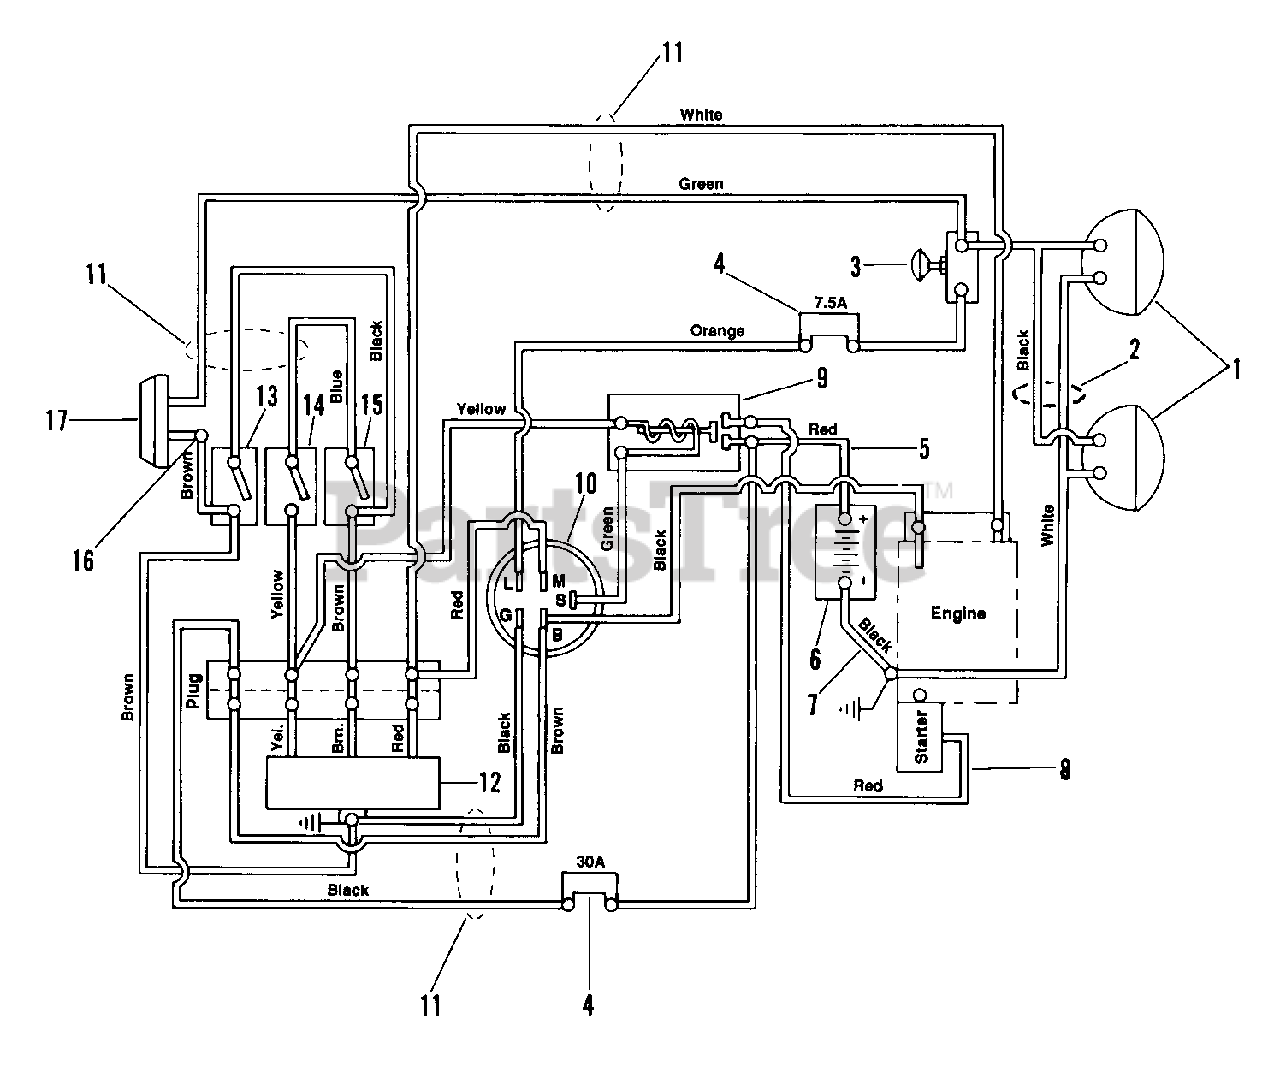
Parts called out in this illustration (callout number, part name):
1	HEAD LIGHT
2	WIRE HARNESS - HEADLIGHT
3	LIGHT SWITCH
4	7.5 AMP FUSE
4	15 AMP FUSE
6	BATTERY
7	CABLE-GROUND
8	STARTER CABLE 16"
9	SOLENOID
10	IGNITION SWITCH ASSY- KAW/KOHL
11	WIRE HARNESS - KOHLER
12	MODUAL - KOHLER
13	SWITCH SEAT
14	SWITCH INTERLOCK
15	SAFETY SWITCH
16	MALE DISCONNECT ADAPTER
17	TAIL LIGHT ASSEMBLY W/BULLET
